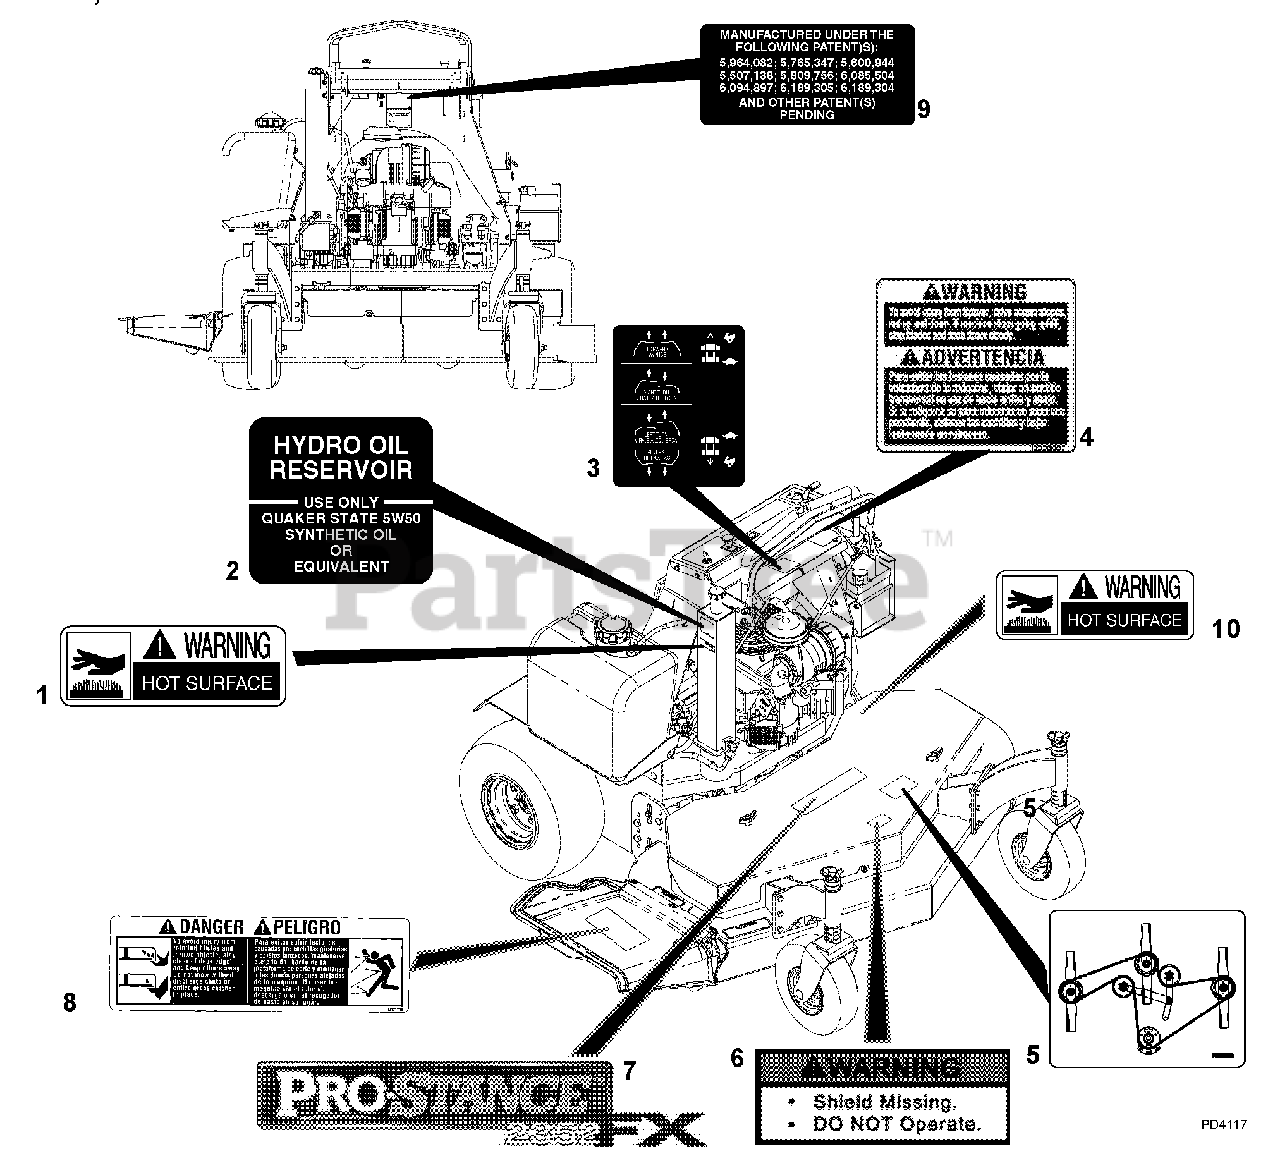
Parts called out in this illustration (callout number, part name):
1	Decal, Warning, Hot Surface
2	Decal, Hydro Oil Reservoir
3	Decal, Directional Control
4	Decal, Danger - Avoid Tipover
5	Decal, Belt Path
6	Decal, Warning, Shield
7	Decal, Pro-Stance 1952FX (994101)
8	Decal, Danger - Thrown Objects
9	Decal, Patent
10	Decal, Warning, Hot Surface (994102)
